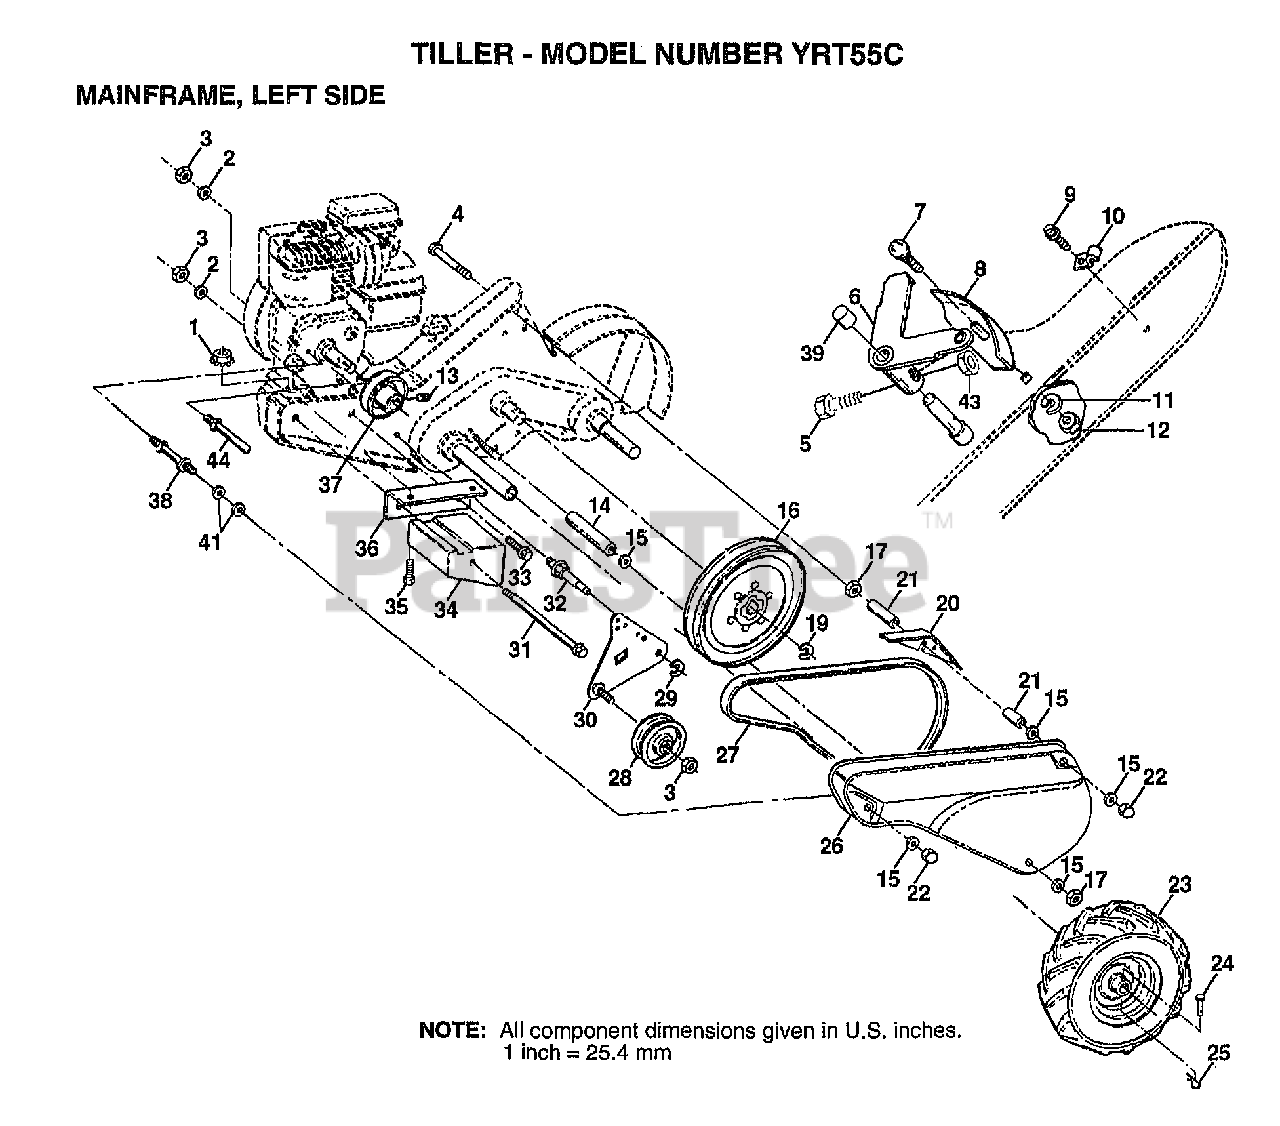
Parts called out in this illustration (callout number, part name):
2	LOCKWASHER
3	NUT.HEX.3/8-16UNC
4	BOLT TI
5	"SCREW-LEVER,SHI"
6	LEVER ASM CRT
7	BOLT
8	PANEL TI
10	CONDIUT CLIP T
11	LOCKWASHER
13	SET SCREW
14	SPACER
15	WASHER
16	SHEAVE.TRANS.
17	NUT.HEX.5/16-18
20	GUARD CRT
21	SPACER.SPLIT
22	NUT TI
23	TIRE TI
23	RIM
24	RIVET.DRILL.1.75
25	RETAINER M
27	BELT-V
28	PULLEY-IDLER TI
29	KLIP RING
30	BRACKET ASM IDLER
31	BOLT CRT
32	SHIFT ARM CRT
33	BOLT
34	COUNTERWEIGHT CRT
35	BOLT
36	BRACKET LH CRT
37	ENGINE PULLEY
38	STUD.GUARD.BELT
39	CAP PLUNGER BLACK
41	WASHER
43	LOCKNUT
44	KEEPER.BELT.ENGINE
